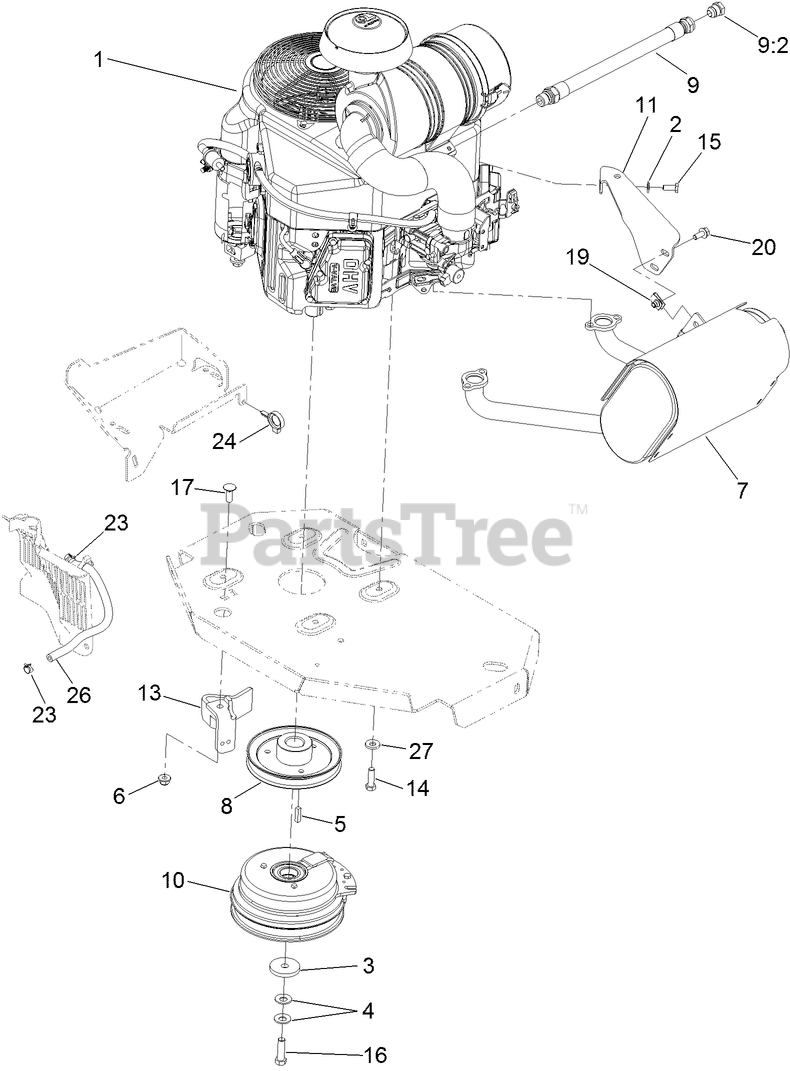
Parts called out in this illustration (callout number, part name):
2	WASHER-SPRING
3	WASHER-CLUTCH
4	WASHER-SPRING
6	NUT-HF, NI
7	MUFFLER
8	SHEAVE
9	OIL DRAIN HOSE ASM
10	CLUTCH KIT
11	BRACKET-MUFFLER
13	CLUTCH-ANCHOR
14	SCREW-HH
15	SCREW-HH
16	SCREW-HH, W/LOCTITE
17	SCREW-CARR
19	NUT-U
20	SCREW-HHF
23	CLAMP-HOSE
24	CLAMP-HOSE
26	HOSE-FUEL
27	WASHER-BELLEVILLE
